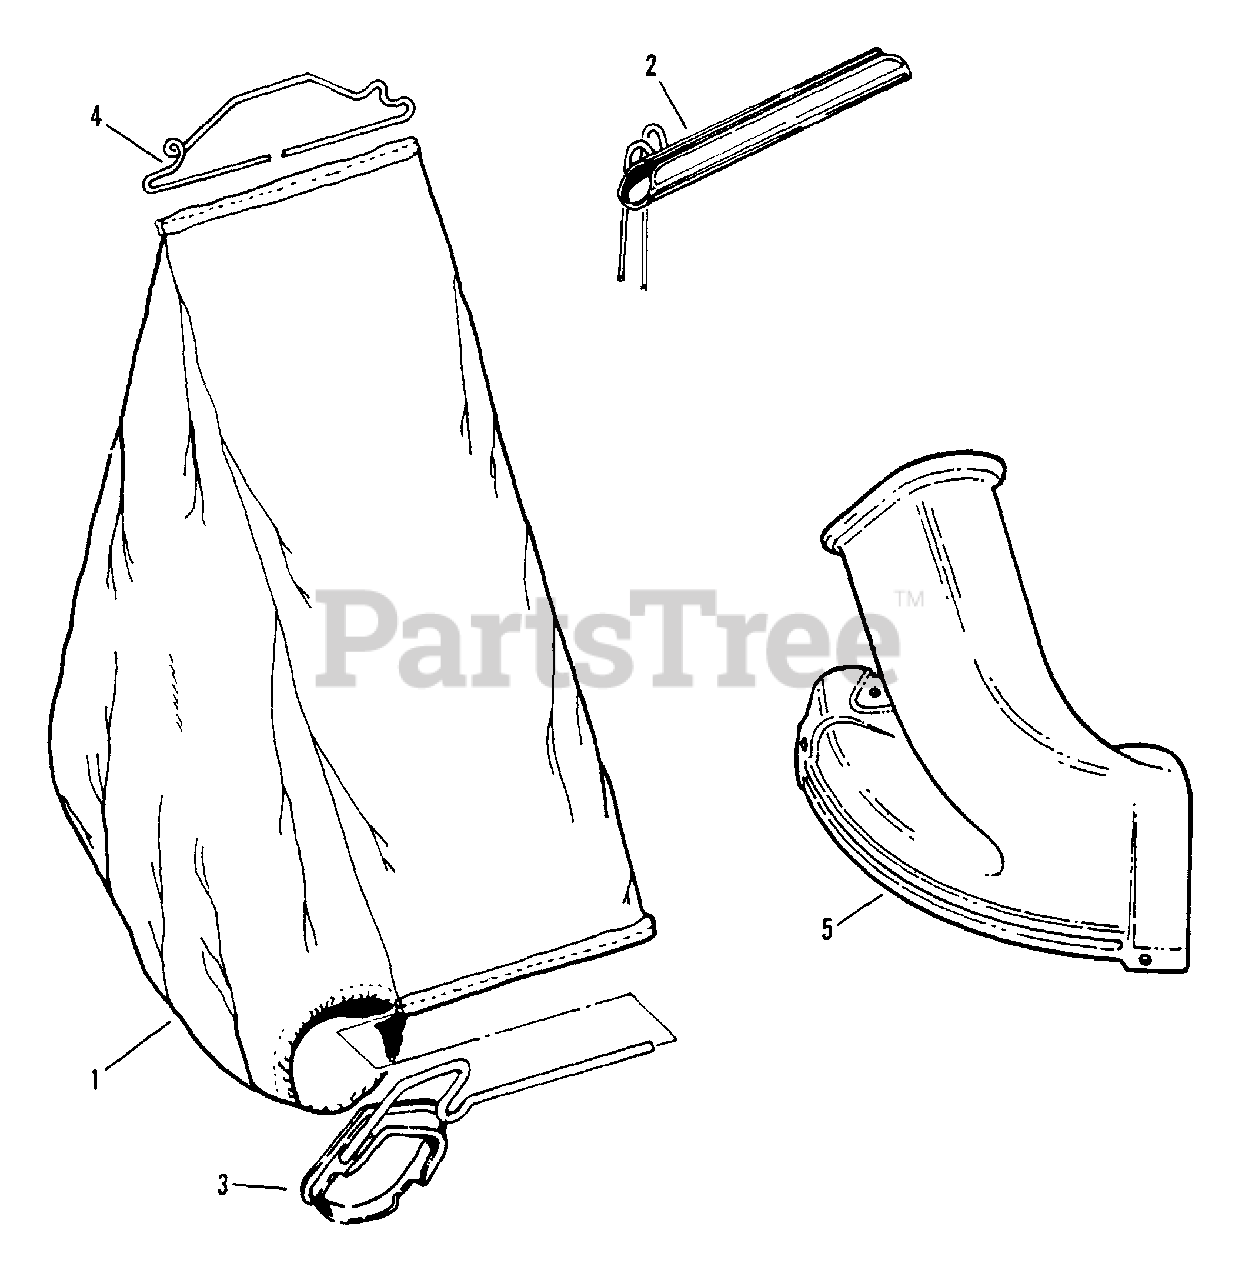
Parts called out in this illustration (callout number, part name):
1	BAG, Grass (Standard)
2	ASSEMBLY, Slider
3	CONNECTOR, Grass Bag
4	WIRE, Bag Connector
5	ADAPTER, Bag
